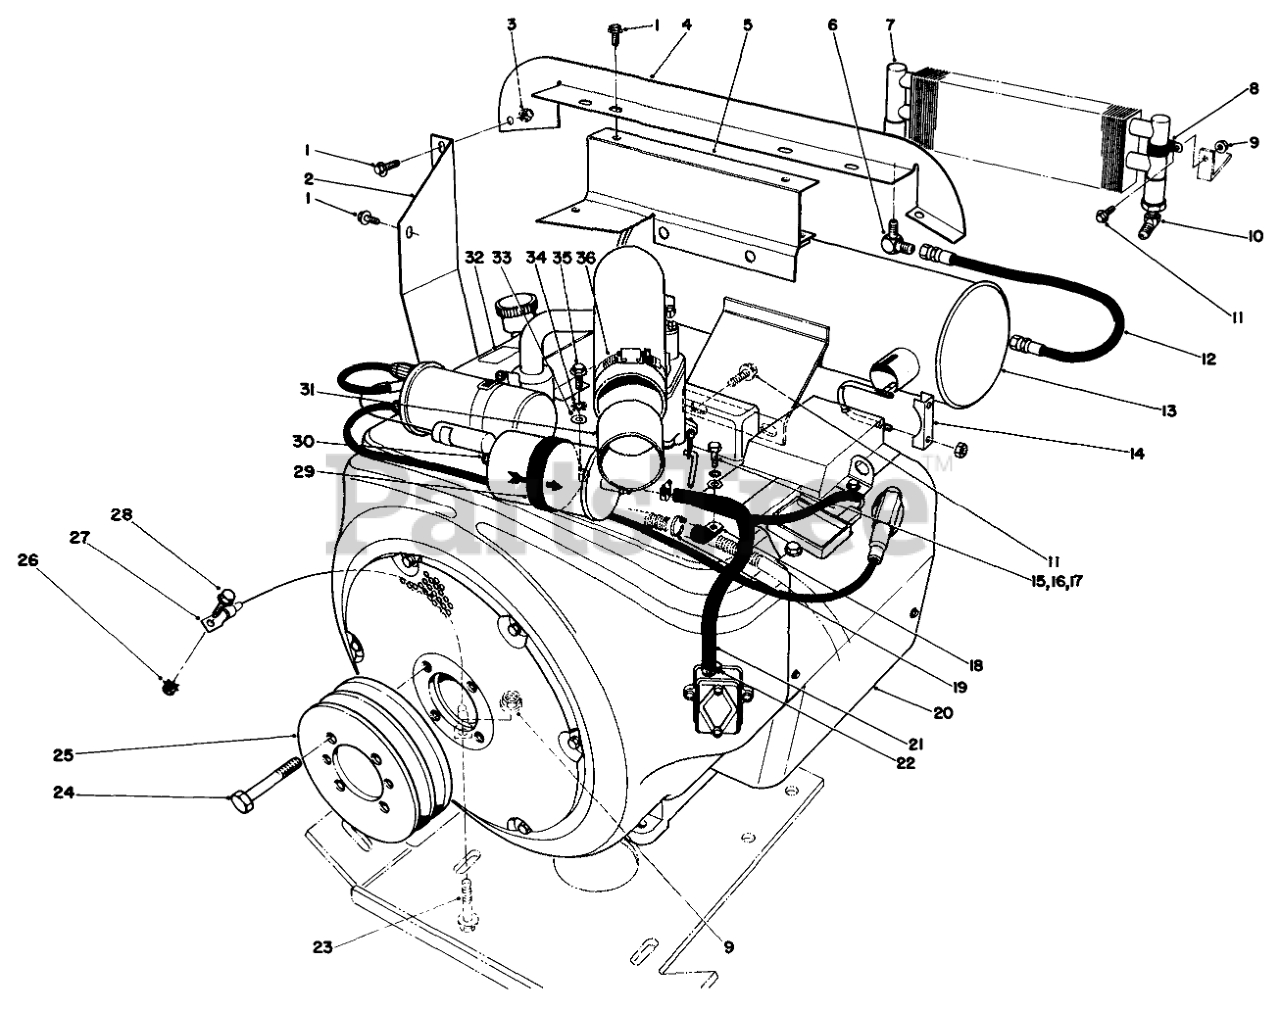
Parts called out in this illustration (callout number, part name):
1	SCREW-HHF
2	Shield-Heat
3	NUT-LOCK, NI
4	Shroud-Engine
5	Bracket-Shield Support
6	90DEG JIC FITTING
7	OIL COOLER
8	CLAMP-R
9	NUT-HHF, WHIZ
10	ELBOW
11	SCREW-HHF
12	OIL HOSE ASM
13	Muffler
14	MUFFLER CLAMP
15	SCREW-HH
16	WASHER-LOCK
17	WASHER-FLAT
18	CLAMP-R
19	TIE-CABLE
20	Engine (Onan Model No. B48G-GA020 Type No. 4348G
21	FUEL LINE
22	CLAMP-HOSE
23	SCREW-HHF
24	SCREW-HH
25	Pulley-Engine
26	NUT-KEPS
27	WIRE ASM
28	SCREW-HHF
29	CLAMP-R
30	FiIter Gas
31	AIR CLEANER ADAPTER
32	SERVICE DECAL
33	WASHER-FLAT
34	WASHER-LOCK
35	SCREW-HWH
36	CLAMP-HOSE
